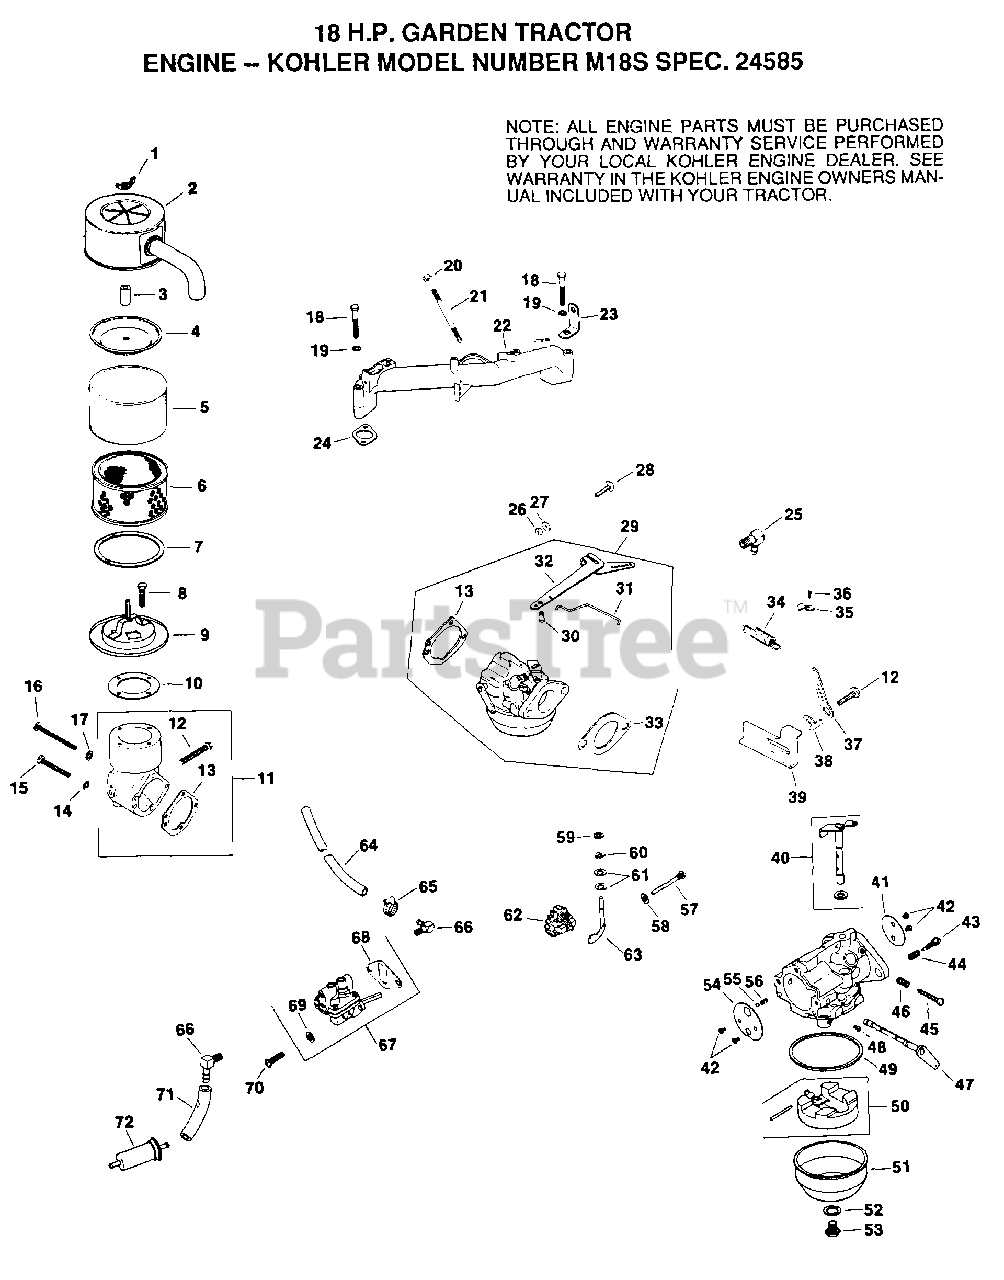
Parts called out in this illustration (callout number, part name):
2	COVER, AIR CLEANER
3	SEAL ELEMENT
4	COVER AIR CLEANER ELEMENT
13	GASKET, AIR CLEANER
22	MANIFOLD, INTAKE
23	STRAP, LIFTING
29	KIT, CARBURETOR
30	BUSHING, LINKAGE
31	LINK, GOVERNOR
32	ARM, GOVERNOR
34	SPRING, GOVERNOR
37	LEVER, SPEED CONTROL
38	STOP, GOVERNOR
39	STOP, HIGH SPEED
40	SHAFT, THROTTLE
53	SCREW, BOWL RETAINER
59	WASHER, PLAIN 1/4
68	GASKET, FUEL PUMP
69	WASHER, PLAIN 1/4
